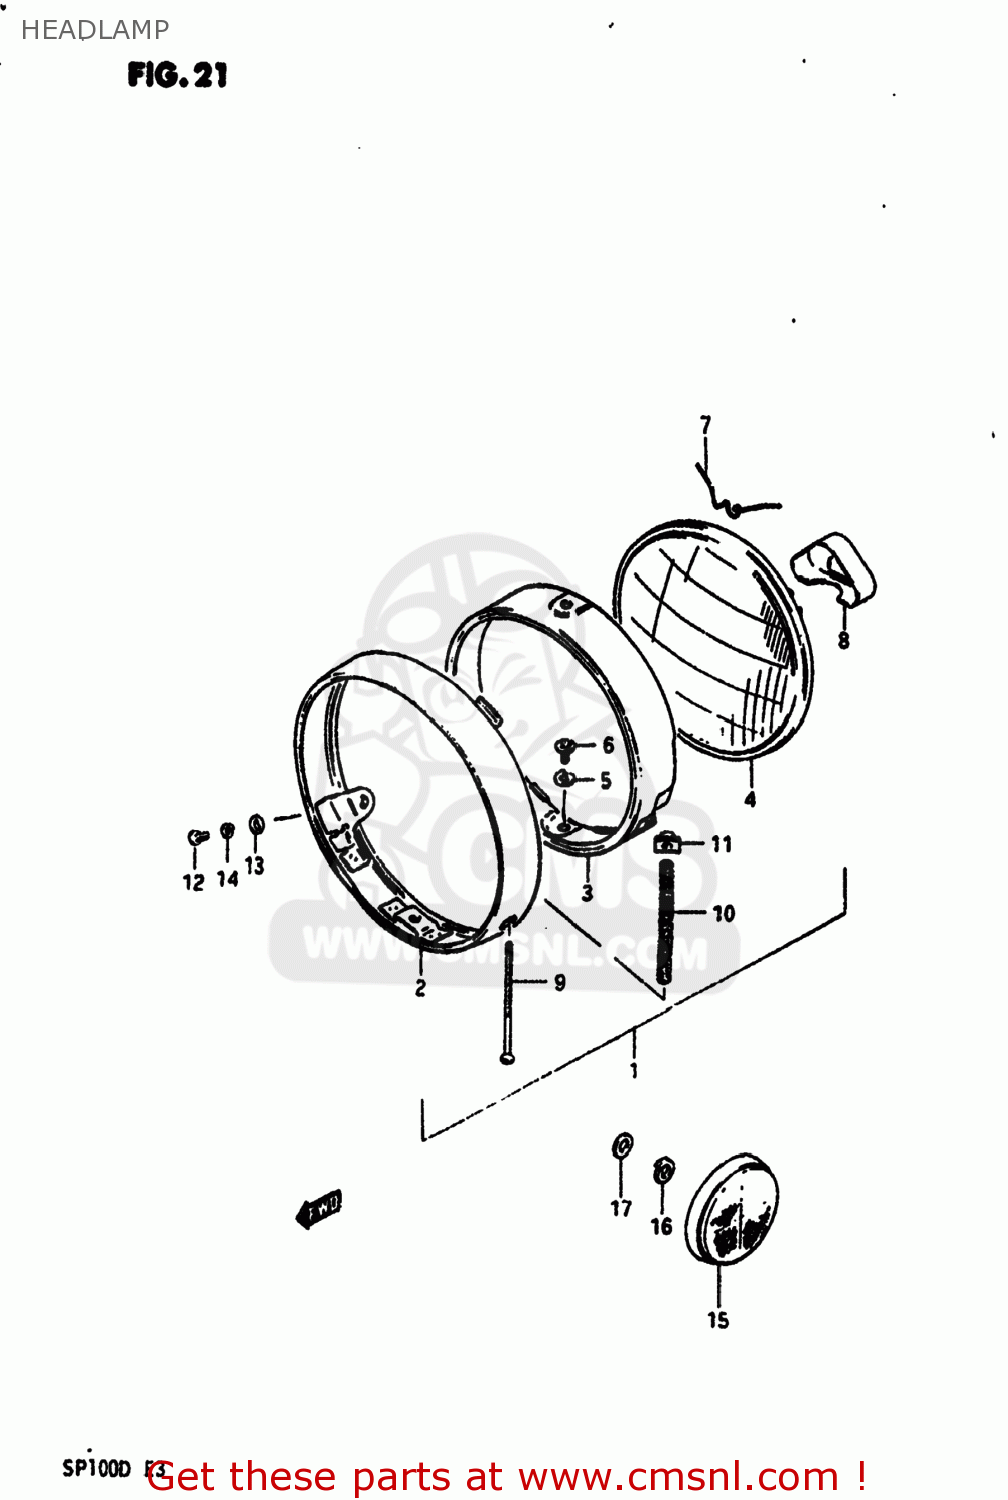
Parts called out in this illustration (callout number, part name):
1	HEADLAMP ASSEMBLY
2	RIM,HEADLAMP
3	RETAINER
4	LAMP UNIT
5	LOCK WASHER
6	SCREW
7	SPRING,HEAD LAMP UNIT
8	COVER
9	SCREW
10	SPRING
11	NUT
12	SCREW
13	WASHER
14	LOCK WASHER
15	REFLEX REFLECTOR,FR
16	LOCK WASHER
17	WASHER
